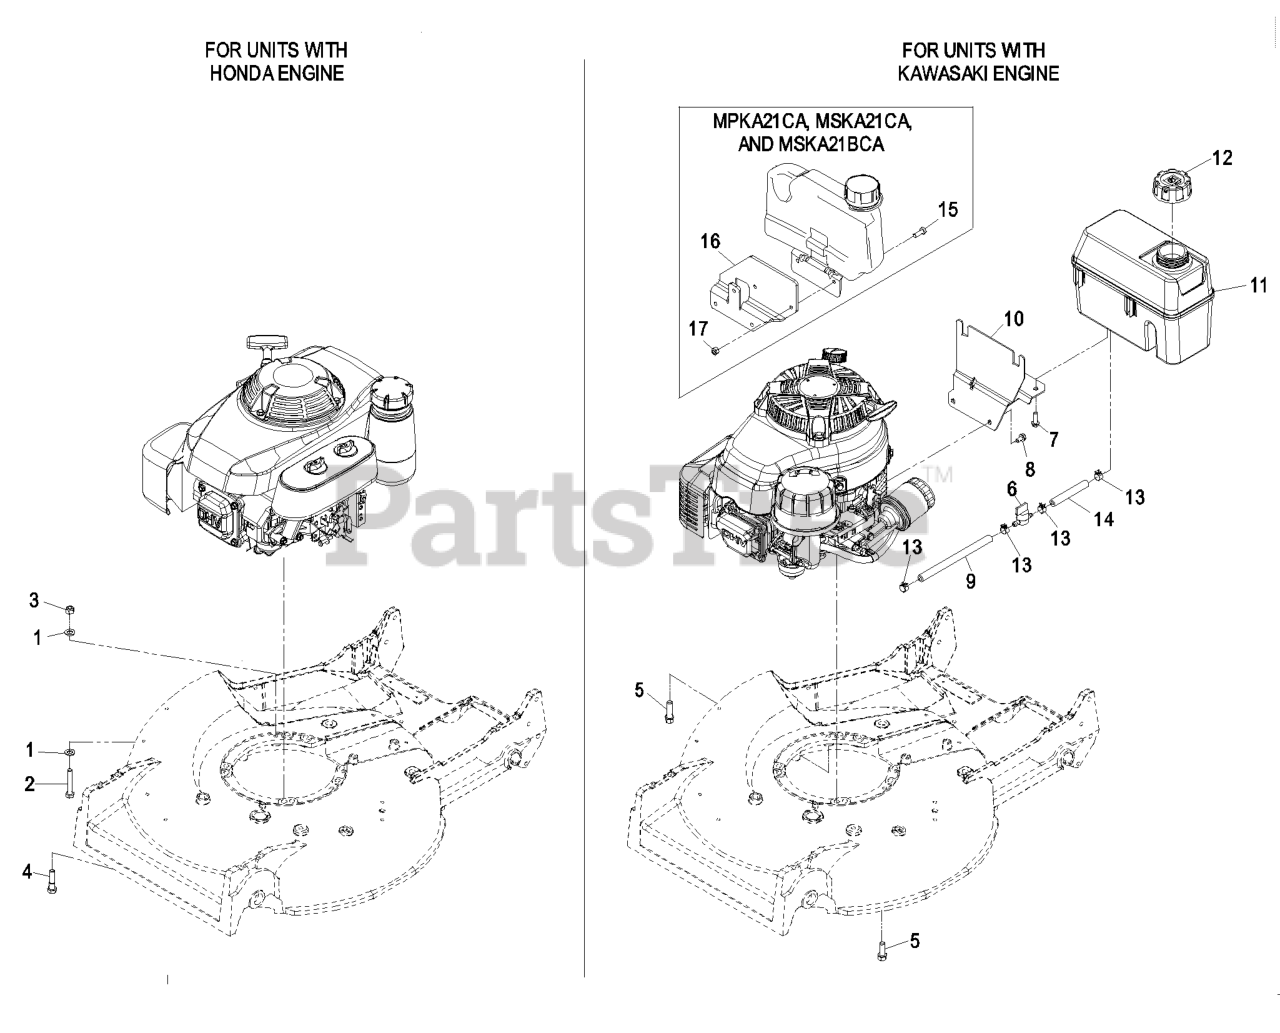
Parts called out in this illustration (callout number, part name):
1	WASHER-PLAIN
2	SCREW-HH
3	NUT-LOCK, NI
4	SCREW-SHOULDER
5	SCREW-TAPTITE
6	VALVE-FUEL
7	SCREW-HWH
8	SCREW-HWH
9	HOSE-FUEL
12	CAP-GAS
13	CLAMP-HOSE
14	HOSE-FUEL
15	SCREW-HH
16	BRACKET-ADAPTER, TANK
17	NUT-LOCK, NI
